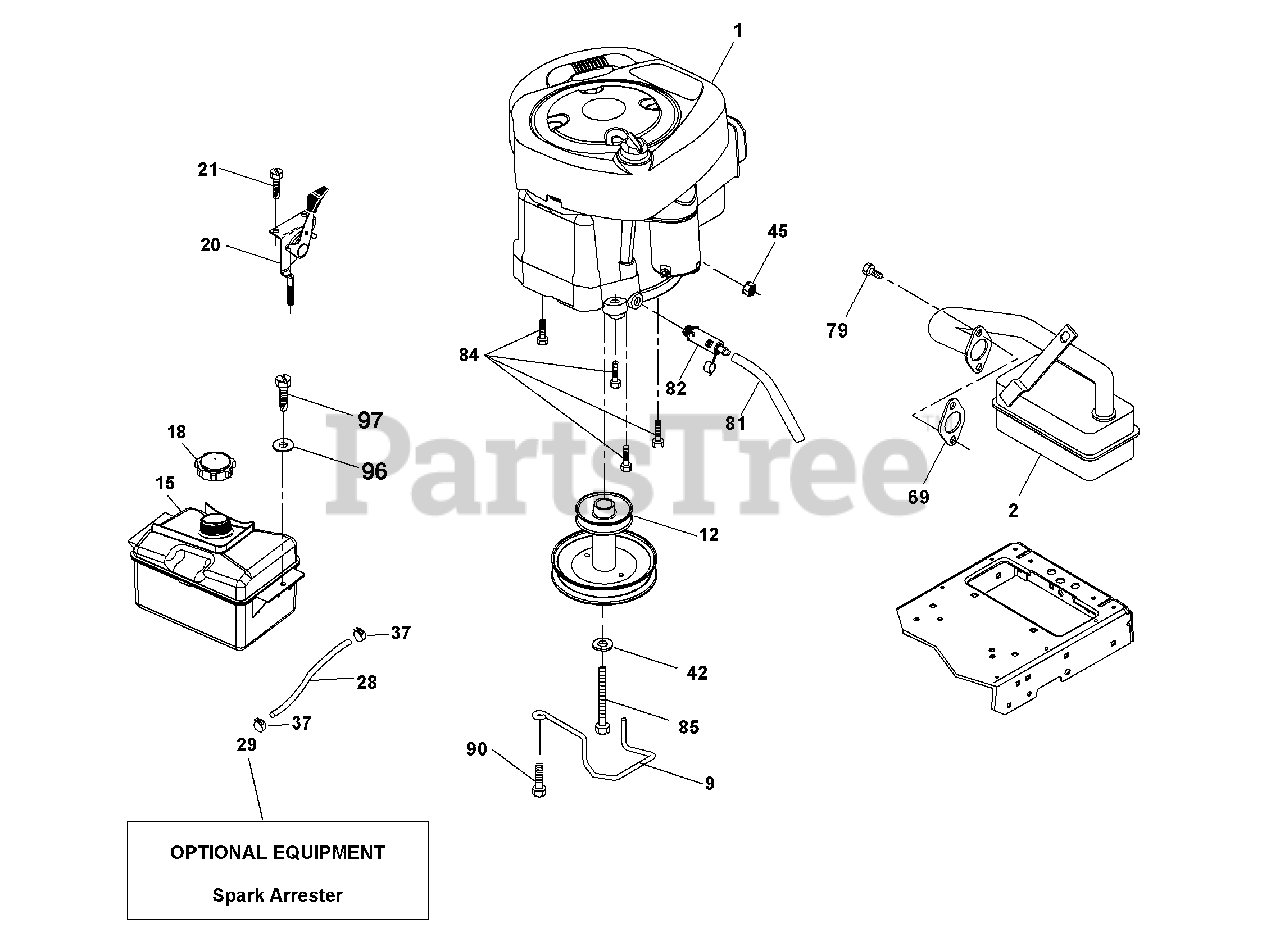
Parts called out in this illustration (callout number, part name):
9	Keeper Belt Engine
12	Pulley Engine
15	Tank Fuel
18	Cap Asm
20	Control Throttle
21	Screw 10 x 3/4 Single Lead-Hex
28	Fuel Line
29	Spark Arrester Kit
37	Clamp Hose
42	Washer Lock 7/16
45	Nut Keps Hex 1/4-20 unc
69	Gasket
79	Screw 5/16-18 x 3/4
81	Tube Drain Oil Easy
82	Plug Drain Oil
84	Screw 3/8-16 x 1/4
85	Bolt Hex 7/16-20 x 4 Gr. 5
90	Screw 3/8-16 x 1
96	Washer 9/32 x 7/8 x 16 Ga.
97	Screw 1/4-20 x 3/4
